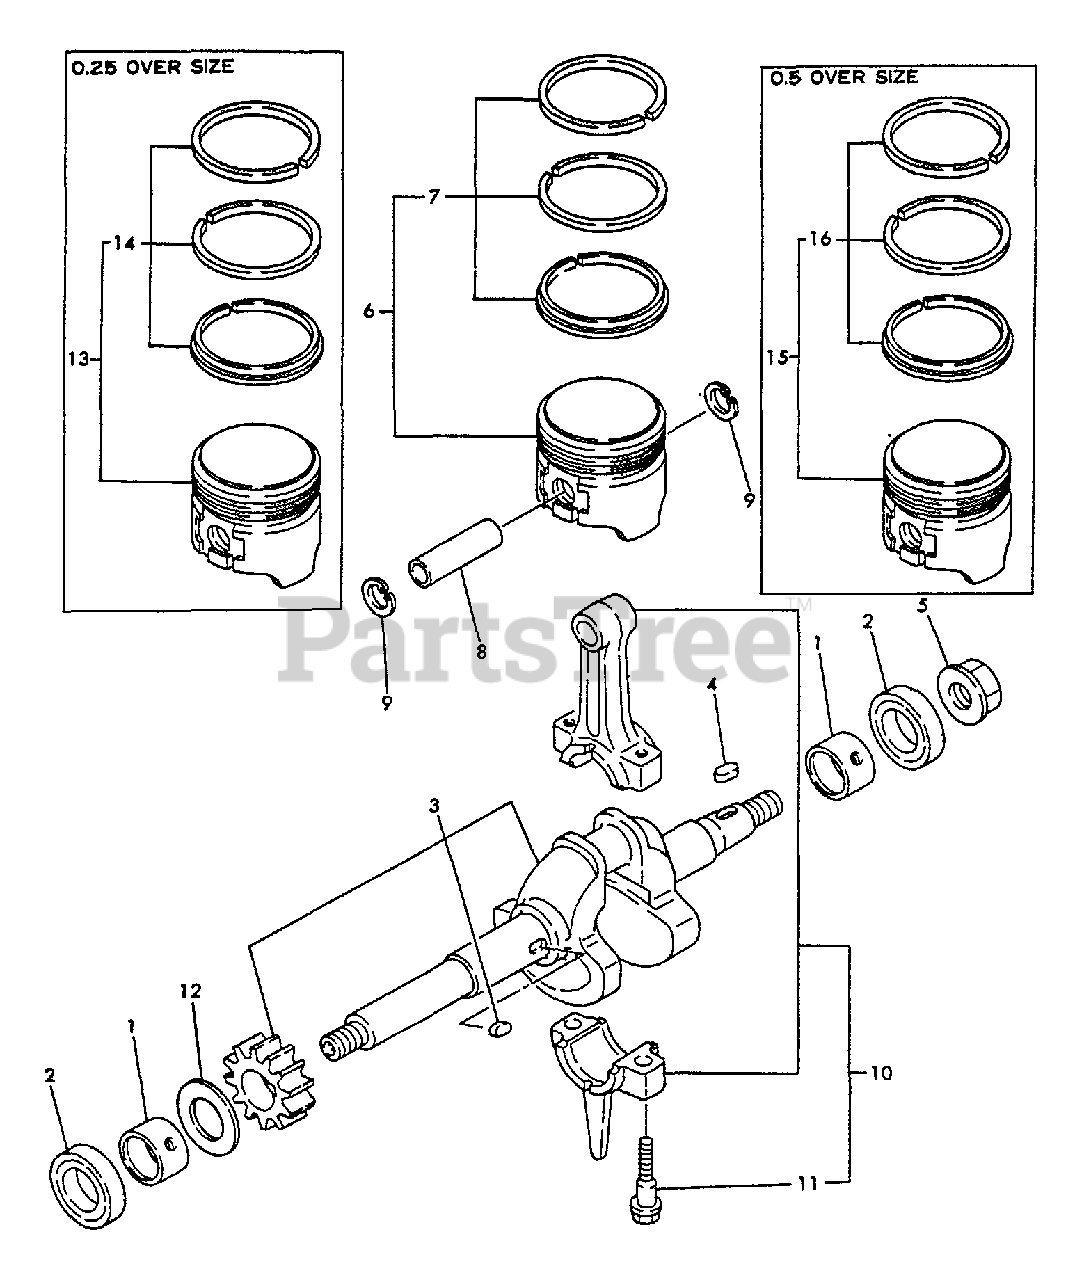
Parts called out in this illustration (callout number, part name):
1	BEARING, MAIN
2	SEAL, OIL
3	CRANKSHAFT ASSY
4	KEY - 4X10
5	NUT - 10 -- FLANGE
6	PISTON ASSY
7	RING SET
8	PIN, PISTON
9	RING, RETAINING - 11
10	CONNECTING ROD ASSY
11	BOLT, ROD
12	WASHER, THRUST
13	PISTON ASSY O.S=0.25
14	RING SET O.S=0.25
15	PISTON ASSY O.S=0.5
16	RING SET O.S=0.5
